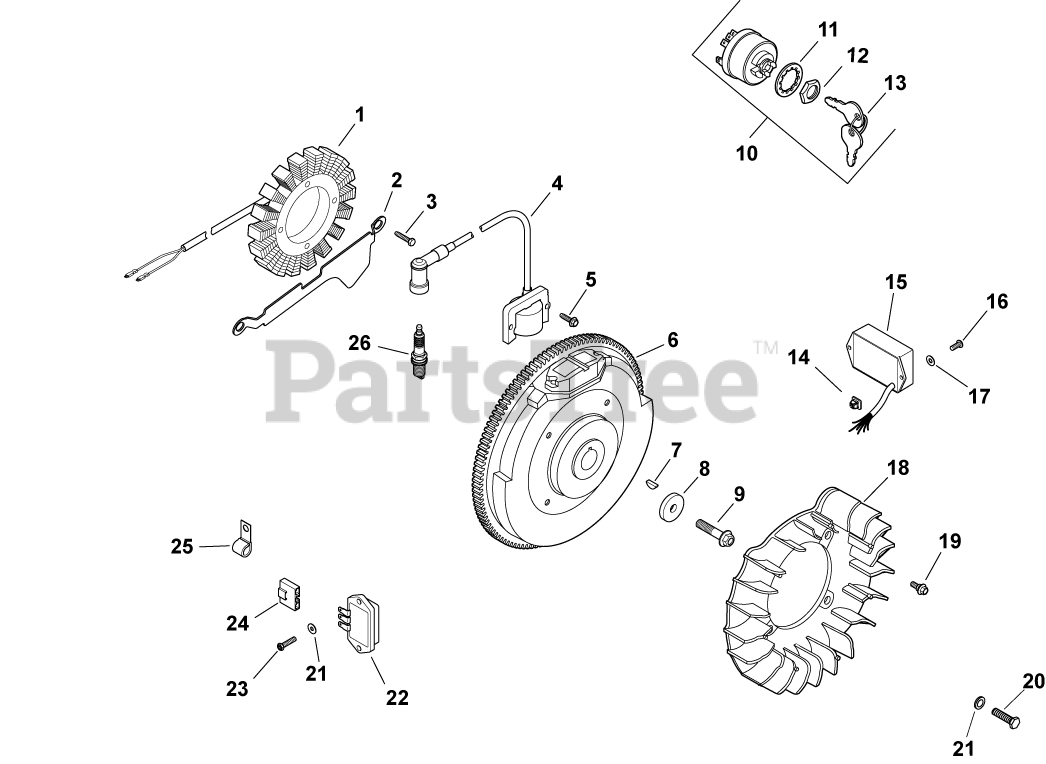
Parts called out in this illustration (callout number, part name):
1	KIT, 15 / 20 AMP STATOR
2	BRACKET, STATOR WIRE
3	SCREW, M5X0.8X25 - (#25086402S)
5	SCREW, SKT THD FRM M5X0.8X25
6	FLYWHEEL ASSEMBLY - USE 24 025 14-S
7	KEY, 3/16" X 5/8"
8	WASHER, FLAT 13/32"
9	SCREW, FLG M10X1.5X45 - (#25086361S)
10	SWITCH ASSY, KEY (KM)-USE 25 099 32-S
11	WASHER, INTERNAL TOOTH
12	NUT, KEY SWITCH
13	KEY, SET -USE 48 340 01-S
14	NUT, PLASTIC
15	MODULE, SPEED ADVANCE-DISCONTINUED SEE PB265
16	SCREW, PHL HD #11-16X1/2"
17	WASHER, FLAT 1/4" (O.D. 1/2")
18	FAN (WITH HOLE)-USE 24 157 16-S
19	BOLT, SHOULDER
20	SCREW, WSH HD TAP #8-18X1/2"
21	WASHER, FLAT 3/16"
22	REG/RECTIFIER (20/25 AMP)-USE 25 403 20-
23	SCREW, PHL HD #11-16X7/8"
24	CONNECTOR, BODY (KM)-USE 25 155 41-S
25	CLIP, CABLE
26	PLUG, SPARK (PRO SERIES)
